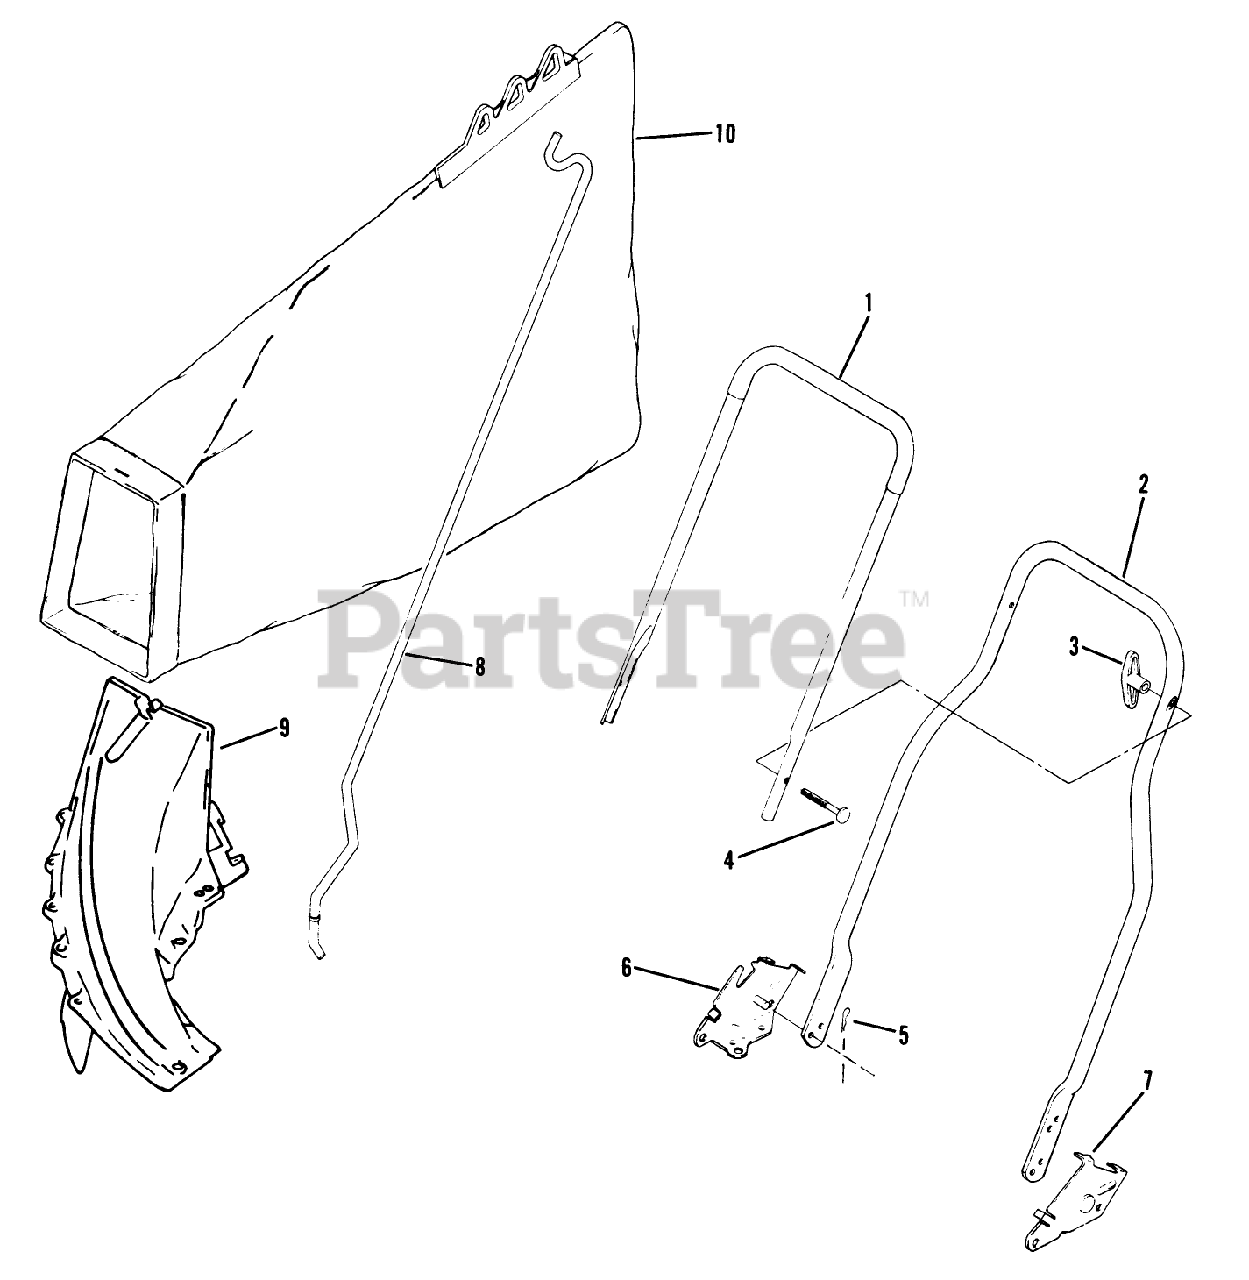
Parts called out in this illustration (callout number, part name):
3	NUT-WING
5	HAIR PIN
8	ROD GRASSBAG
10	89802 LB WHOLE GOODS
